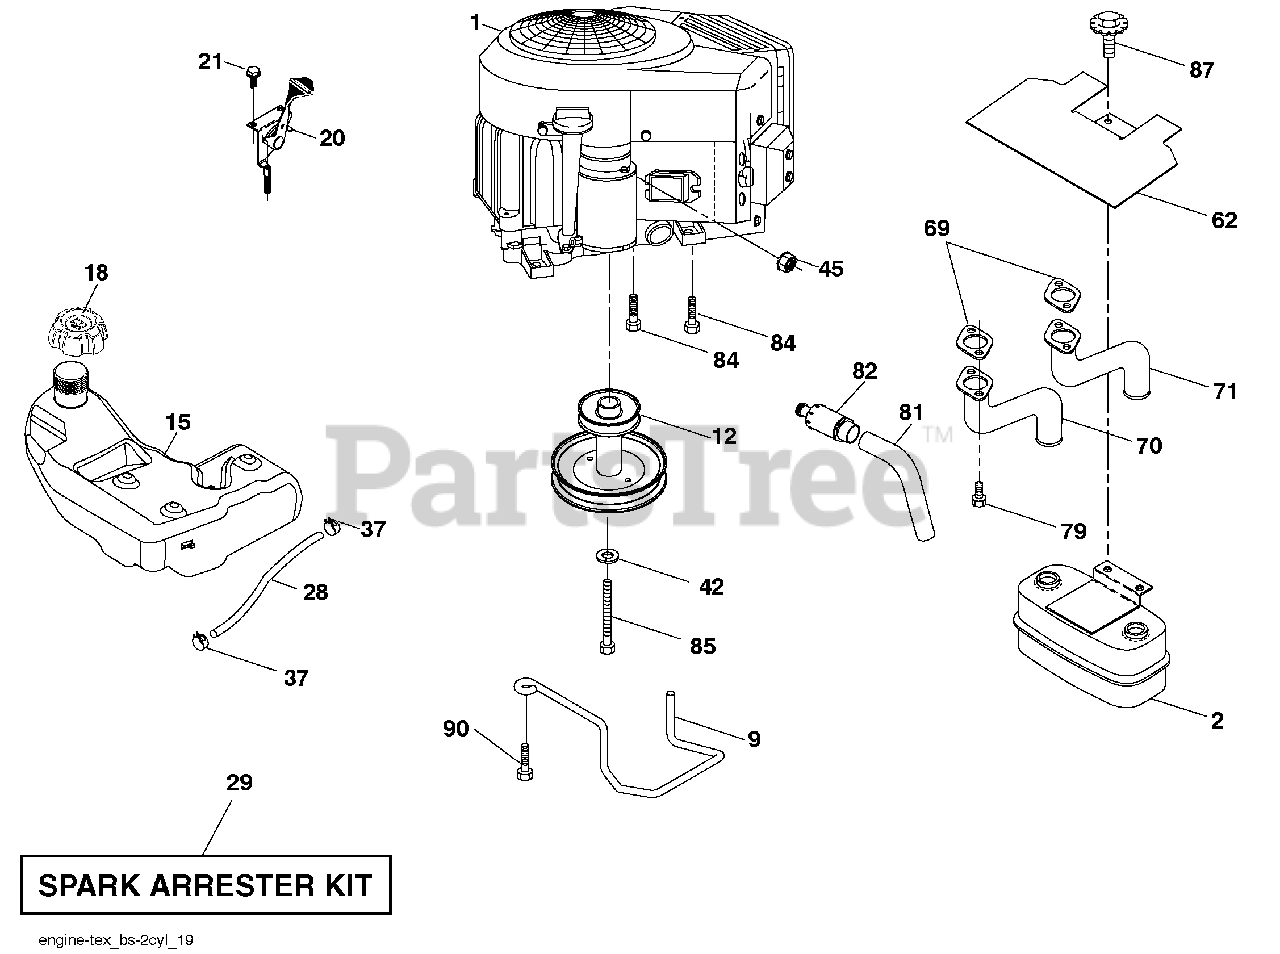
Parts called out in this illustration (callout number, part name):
2	Muffler
9	Keeper Belt Engine
12	Pulley Engine
15	Tank Fuel 3.0
18	Cap Asm
20	Control Throttle
21	Screw #10 x 0.750 BOS Thread
28	Fuel Line
29	Spark Arrester Kit
37	Clamp Hose
42	Washer Lock 7/16
45	Nut Keps Hex 1/4-20 unc
62	Shield Heat Muffler
69	Gasket
70	Exhaust Tube RH
71	Exhaust Tube LH
79	Screw Socket Head 5/16-18 x 1
81	Tube Drain Oil Easy
82	Plug Drain Oil
84	Screw 3/8-16 x 1-1/4
85	Bolt Hex 7/16-20 x 4 x 5 Ga.-1.5
87	Bolt 5/16-18 x 3/4
90	Screw 3/8-16 x 1
